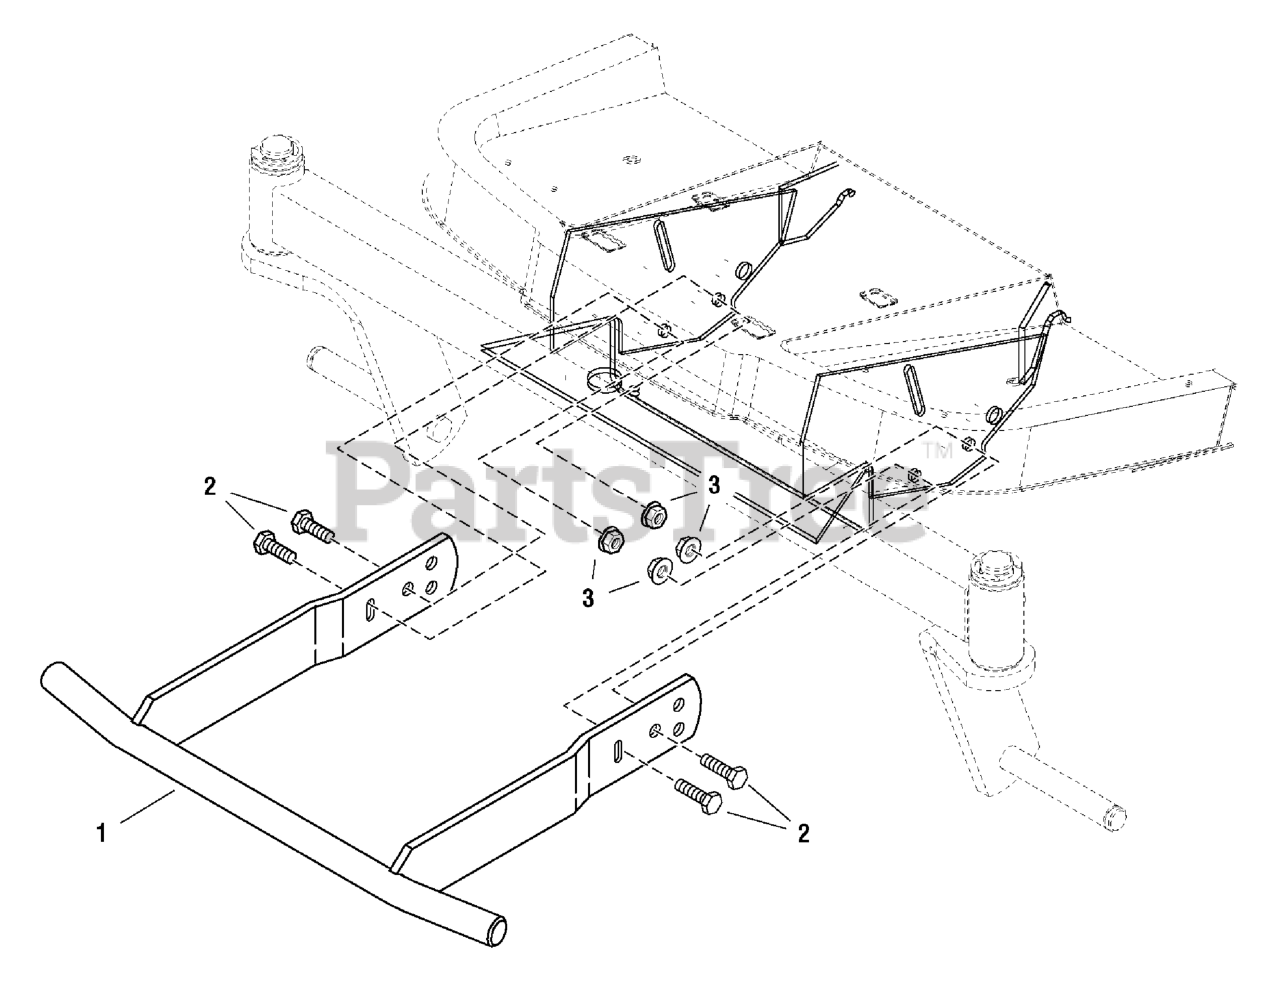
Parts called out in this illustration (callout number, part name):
1	Bumper Assembly
2	Capscrew, Hex, 5/16-18 x 7/8
3	Nut, Flange Lock, 5/16-18
